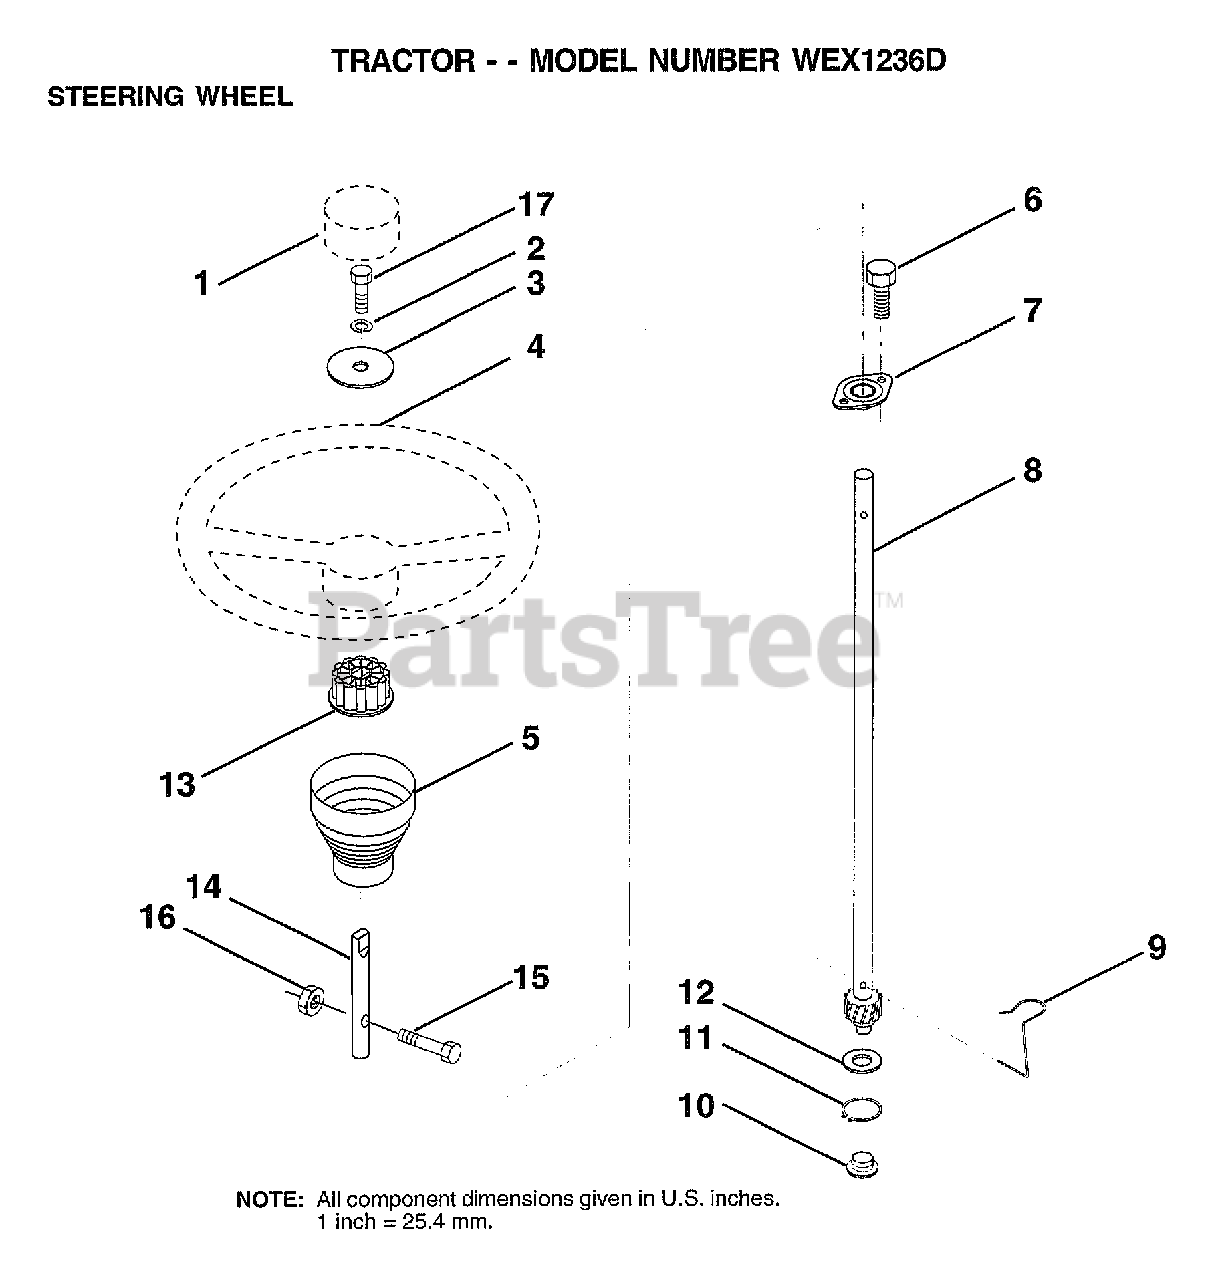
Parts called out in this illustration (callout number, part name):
1	ST WHL INSERT CAP
2	LOCKWASHER
3	WASHER
5	SLEEVE STEERING
6	"SCREW-TT,10-32 FL"
7	BUSHING.STR.623
8	SHAFT.STEERING.LR
9	STEERING CLIP
10	BUSHING STEER LWR
11	RING
12	WASHER LT
13	ADAPTER LT
14	EXT SHAFT STEERIN
15	BOLT
16	NUT
17	BOLT
